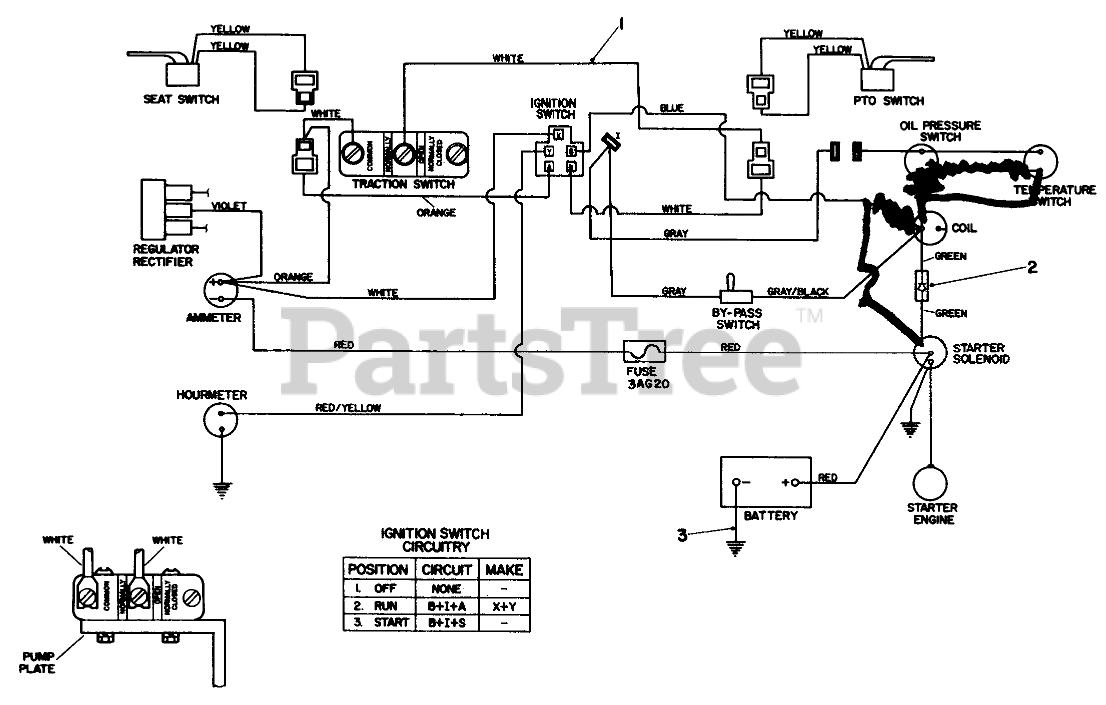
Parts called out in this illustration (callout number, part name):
1	Wire Harness (Incl. Ref. #2)
2	JUMPER WIRE ASM
3	BATTERY GROUND WIRE
